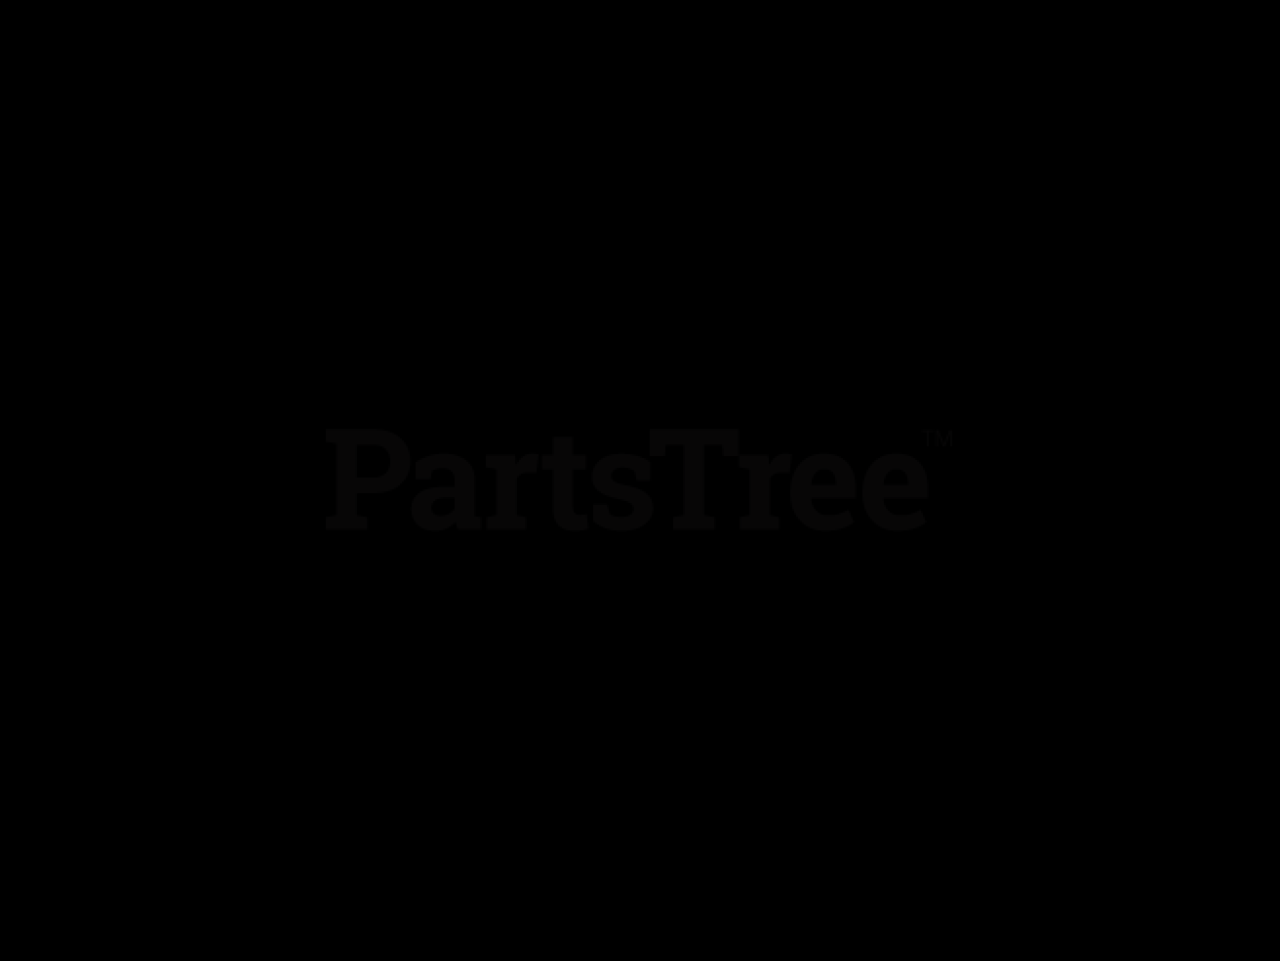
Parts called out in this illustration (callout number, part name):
1	Bolt, Hex .312-18 x 1.50
2	Jam Nut, .312-18
3	Bolt, Hex M12-1.75 x 50
4	Nut, Spin Lock Flange M12-1.75
5	Chain, Link
6	Cap, Vinyl .50 ID x 1.50 LG x .055
7	Bolt, Hex .312-18 x 2.00
8	Bracket, Deck Leveling
9	Bolt, Hex .38-16 x 1.00
10	Bearing, .75 x .875 x 1.00
11	Pin, Weldment Mower Mounting
12	Nut, Nylock Flanged .375-16
13	Bolt, Hex .50-13 x 2.00
14	Weldment Deck Stablizing Arm
15	Nut, Nylock Flanged .50-13
